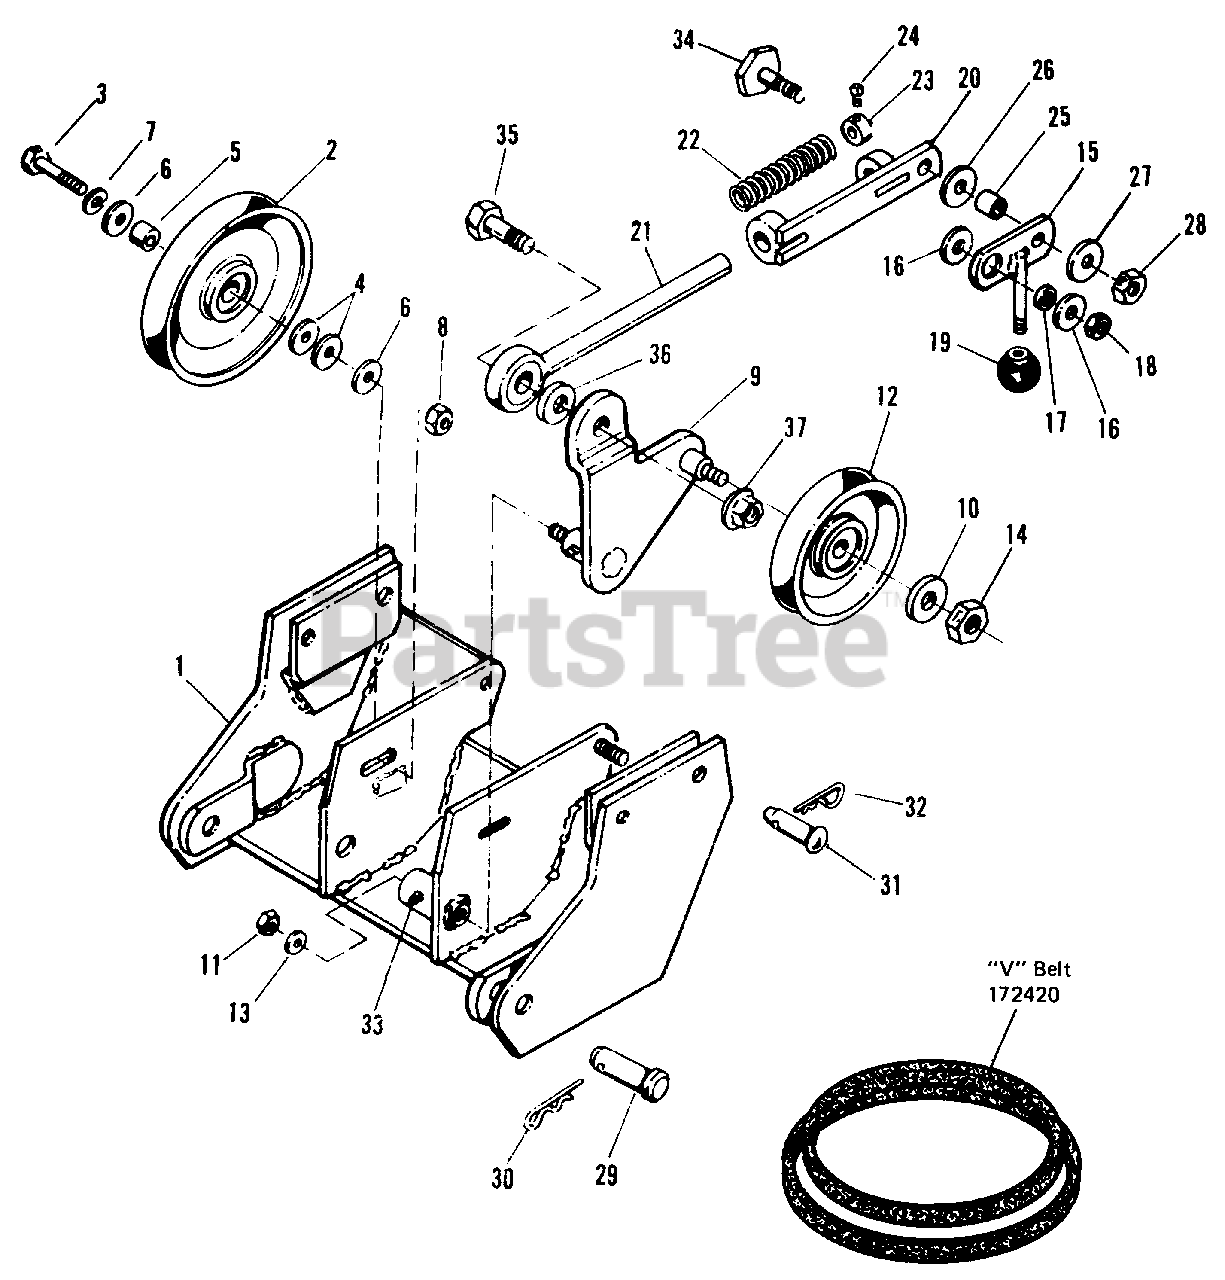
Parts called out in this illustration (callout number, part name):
1	Support Assembly
3	Hex Capscrew, 3/8-24 x 1-3/4"
4	Plain Washer, 5/16
7	Lock Washer, 3/8
8	Special Nut, Flange
9	Lever Assembly
10	Plain Washer, 5/16
11	Hex Nut Lock, 3/8-16
14	Hex Nut Centerlock, 1/2-13
15	Lever Assembly
16	Plain Washer, 3/8
18	Jam Nut, 3/8-16
20	Rod Guide Assembly
23	Set Collar
24	Set Screw, 1/4-20 x 3/8
26	Special Washer
27	Plain Washer, 3/8
28	Hex Nut, Full Lock, 3/8-16
30	Safety Spring Clip
32	Hair Pin Clip
33	Grease Fitting
35	Shoulder Bolt
36	Washer Plain, 1/2
37	Nut Flange, 3/8-16
